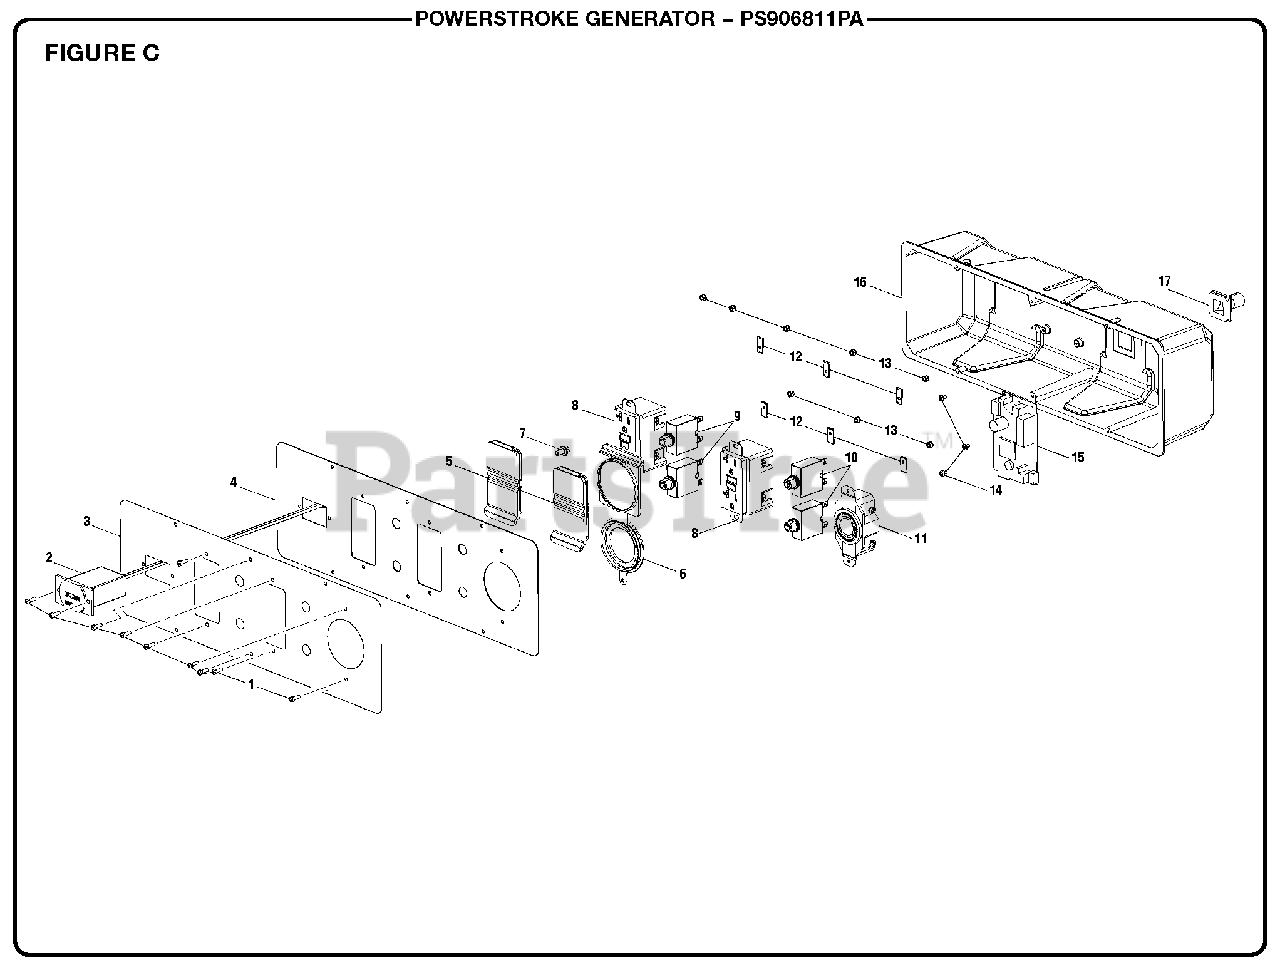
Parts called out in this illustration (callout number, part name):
1	Screw (6-20 x 3/8 in.)
2	Hour Meter
3	Outlet Panel Label
4	Front Panel
5	120 Volt Outlet Covers
6	240 Volt Outlet Covers
7	Bolt (M5 x 10 mm, Hex Flange Hd.)
8	120 Volt Duplex GFCI Receptacle
9	Circuit Breaker (20 Amp, 125 Volt)
10	Circuit Breaker (30 Amp)
11	Twist Lock Receptacle (120/240 Volt, 30 Amp, L14-30R)
12	U- Clip Nut (#6)
13	Nut (#6-32)
14	Screw (M3 x 5 mm,)
15	Battery Charger Assembly
16	Control Box (Back Panel)
17	Rubber Boot (Control Panel Assembly)
